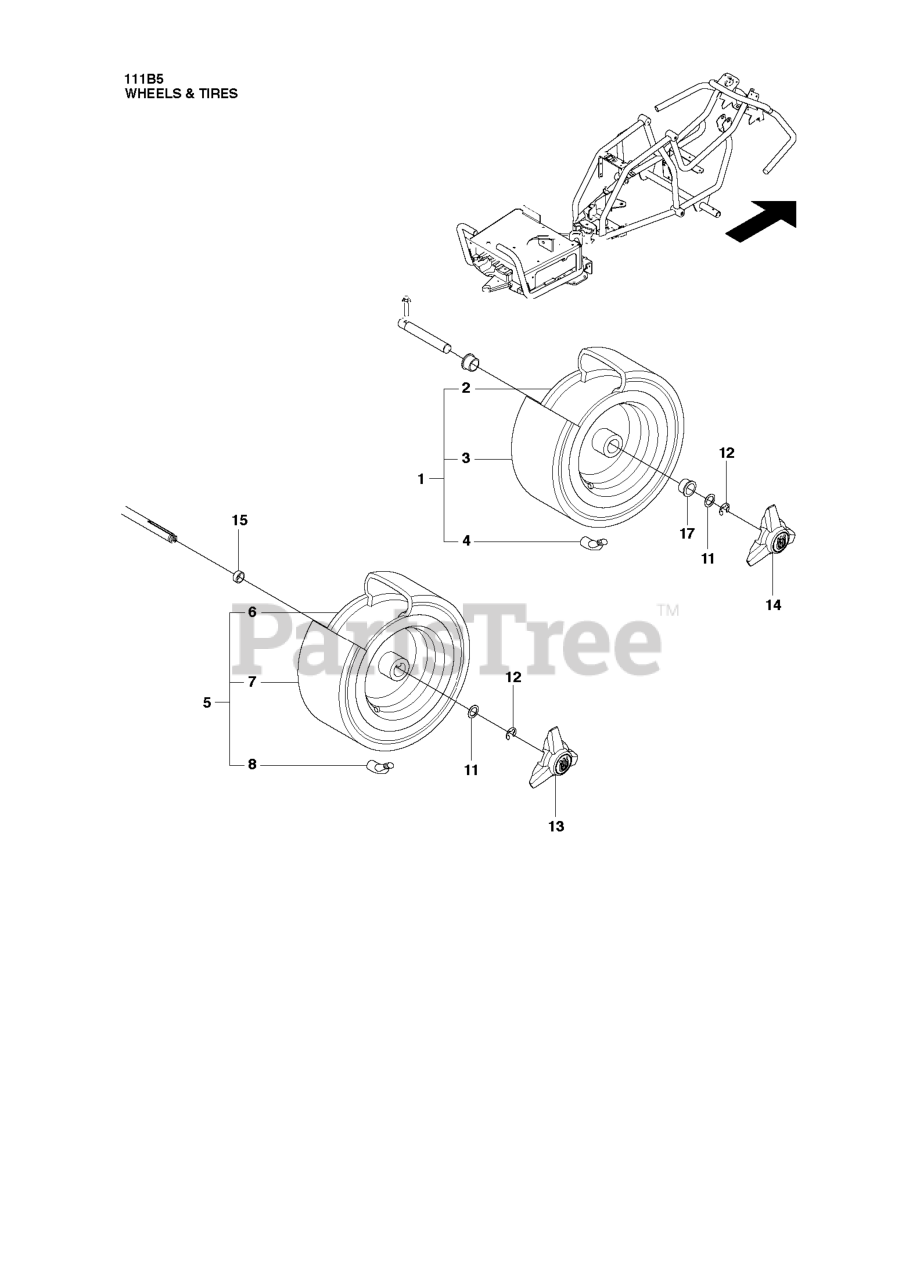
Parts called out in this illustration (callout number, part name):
4	VALVE
8	VALVE
12	RETAINING RING
